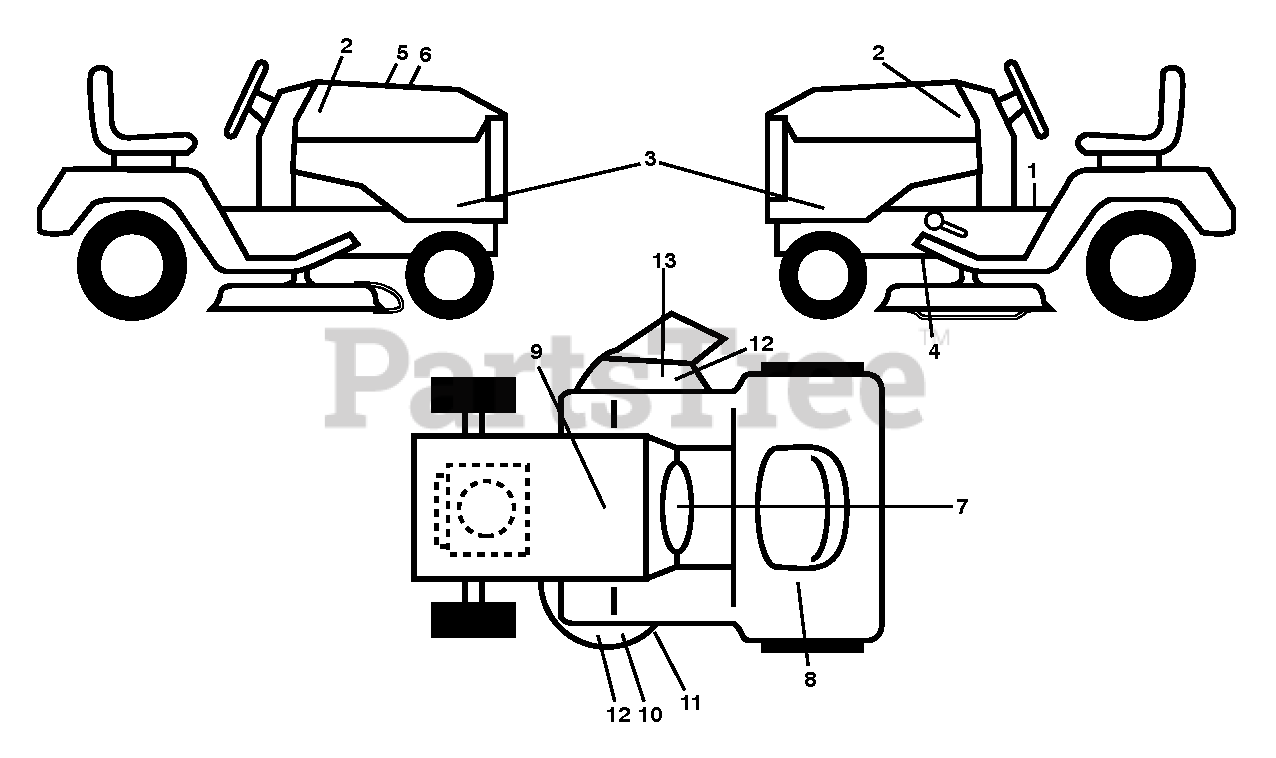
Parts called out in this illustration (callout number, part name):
1	DECAL.FENDER.WARNING.ENGLISH
2	DECAL.BADGE.170MM.TEXTLOGO.
3	Decal, Side Panel HUSQGT YT4
4	DECAL.PEDAL.HUSQ.CROWN
5	DECAL.WARNING.CUST.RESP.E85.
6	Decal, Replacement Kawasaki FR TLB
7	DECAL, WARNING SPARK ARRESTOR
8	DECAL.RESERVEFUELSELCTR.ENG
9	DECAL BTRY SYMBOLS
10	DECAL.HV.REINFORCED.DECKS.2012
11	DECAL, BELT ROUTING
12	DECAL.DECK.CLEARCUT.NOSTEP
13	DECAL.TRACT/ZTR.DECKWARN.HUSQ
